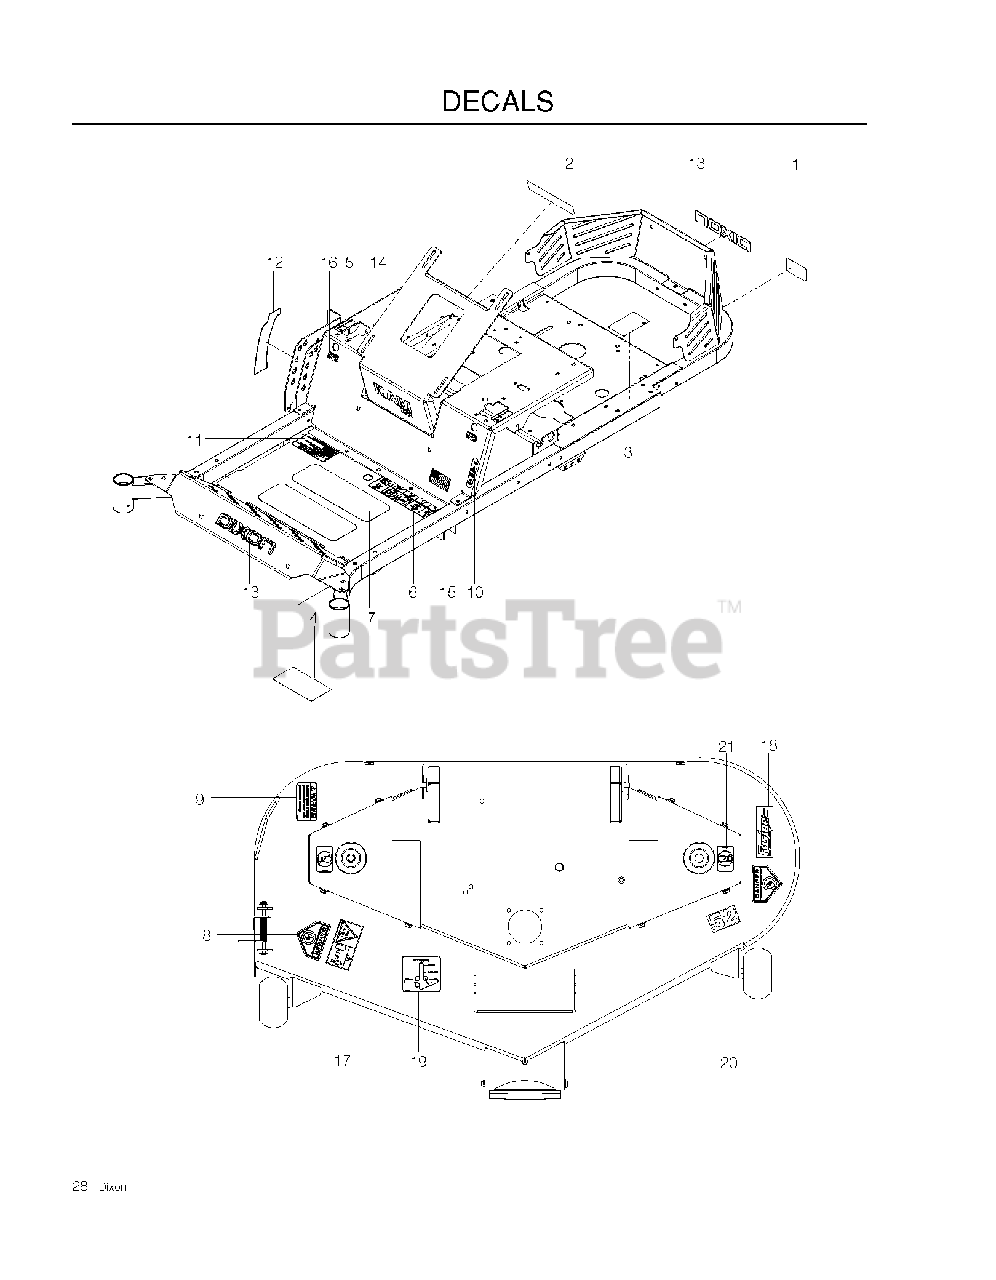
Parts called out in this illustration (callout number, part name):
1	DECAL, PROP. 65
2	DECAL, BATTERY
3	DECAL, DO NOT MOUNT
4	DECAL, SERVICE
5	DECAL, MOTION CONTROL
6	DECAL, SAFETY WARNING
7	DECAL, WARNING
8	DECAL, CPSC
9	DECAL, CAUTION
10	DECAL, PARK BRAKE
11	ANTI-SKID PAD
12	DECAL, HEIGHT
13	DECAL, DIXON LOGO, DOMED
14	DECAL, RAM ZTR, 2008
15	DECAL, FLAG
16	DECAL, F.S.T.
17	DECAL, EURO SEVERING
18	DECAL, FUSION
19	DECAL, BELT ROUTING
20	DECAL, 61
21	DECAL, NO STEP
